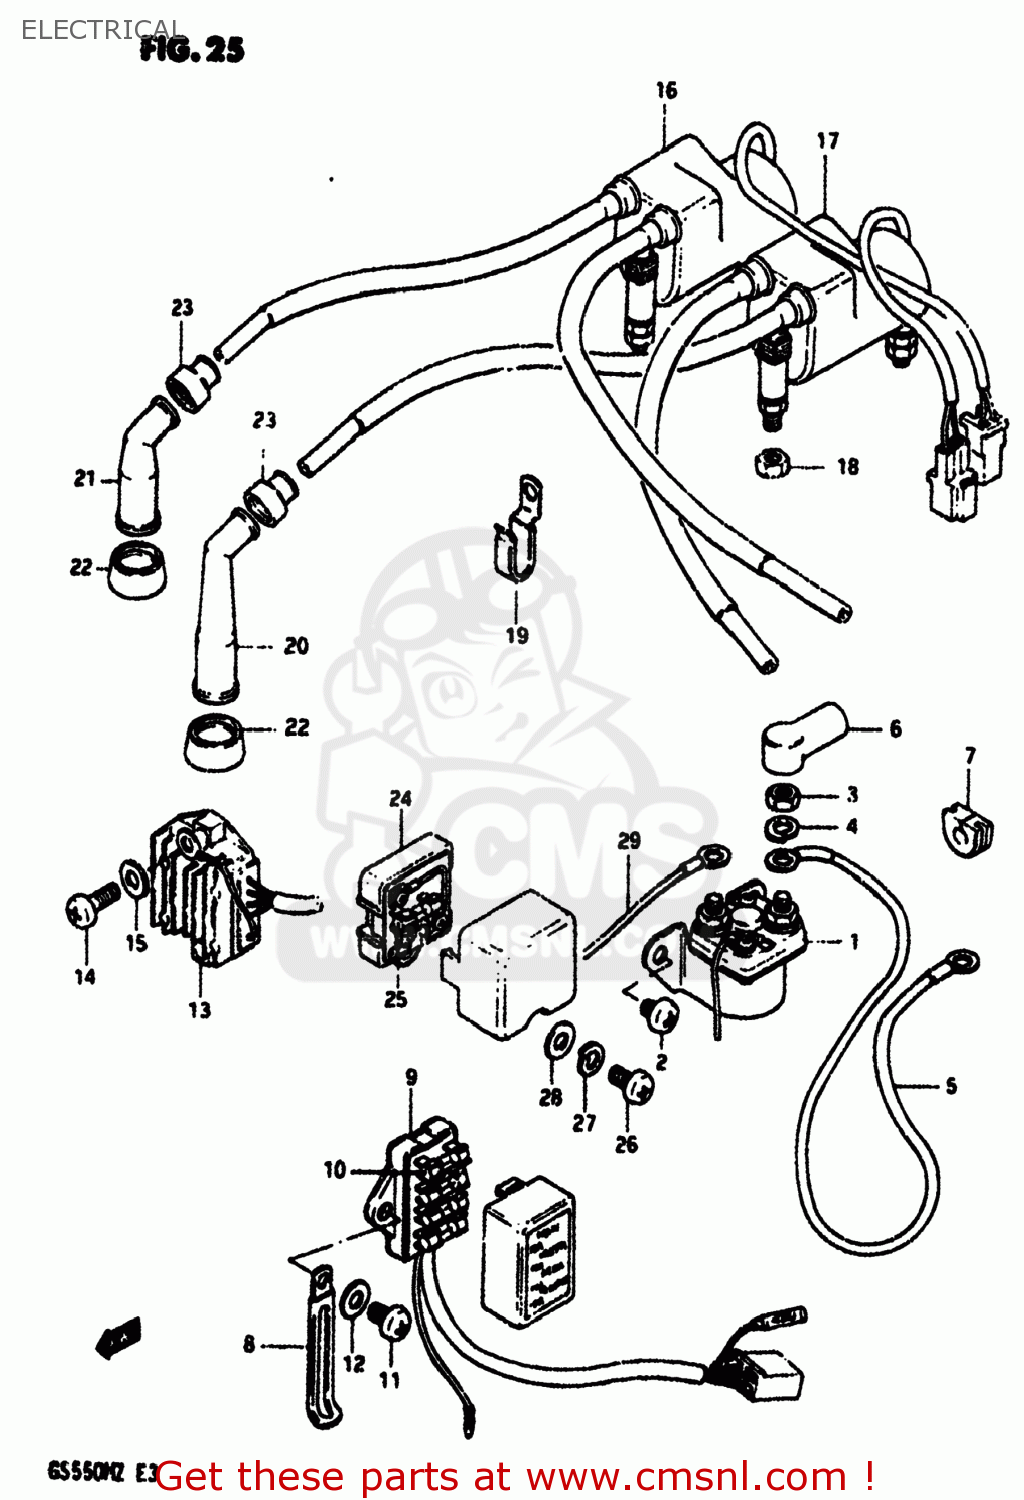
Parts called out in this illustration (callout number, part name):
1	RELAY ASSY,STARTING MOTOR
2	SCREW
3	NUT 6MM
4	LOCK WASHER
5	WIRE,STARTER MOTOR LEAD
6	CAP,STARTER RELAY
7	GROMMET,STARTER CABLE
8	CLAMP
9	BOX ASSEMBLY,FUSE
10	FUSE(15A)
11	SCREW 6X12
12	WASHER
13	RECTIFIER ASSEMBLY
14	SCREW
15	WASHER
16	COIL ASSEMBLY,IGNITION
17	COIL ASSEMBLY,IGNITION
18	NUT
19	CLAMP
20	CAP ASSY,SPARK PLUG
21	CAP,SPARK PLUG
22	SEAL,SPARK PLUG
23	SEAL,SPARK PLU
24	TERMINAL ASSEMBLY,POWER SO
25	FUSE(10A)
26	SCREW
27	LOCK WASHER
28	WASHER
29	WIRE
